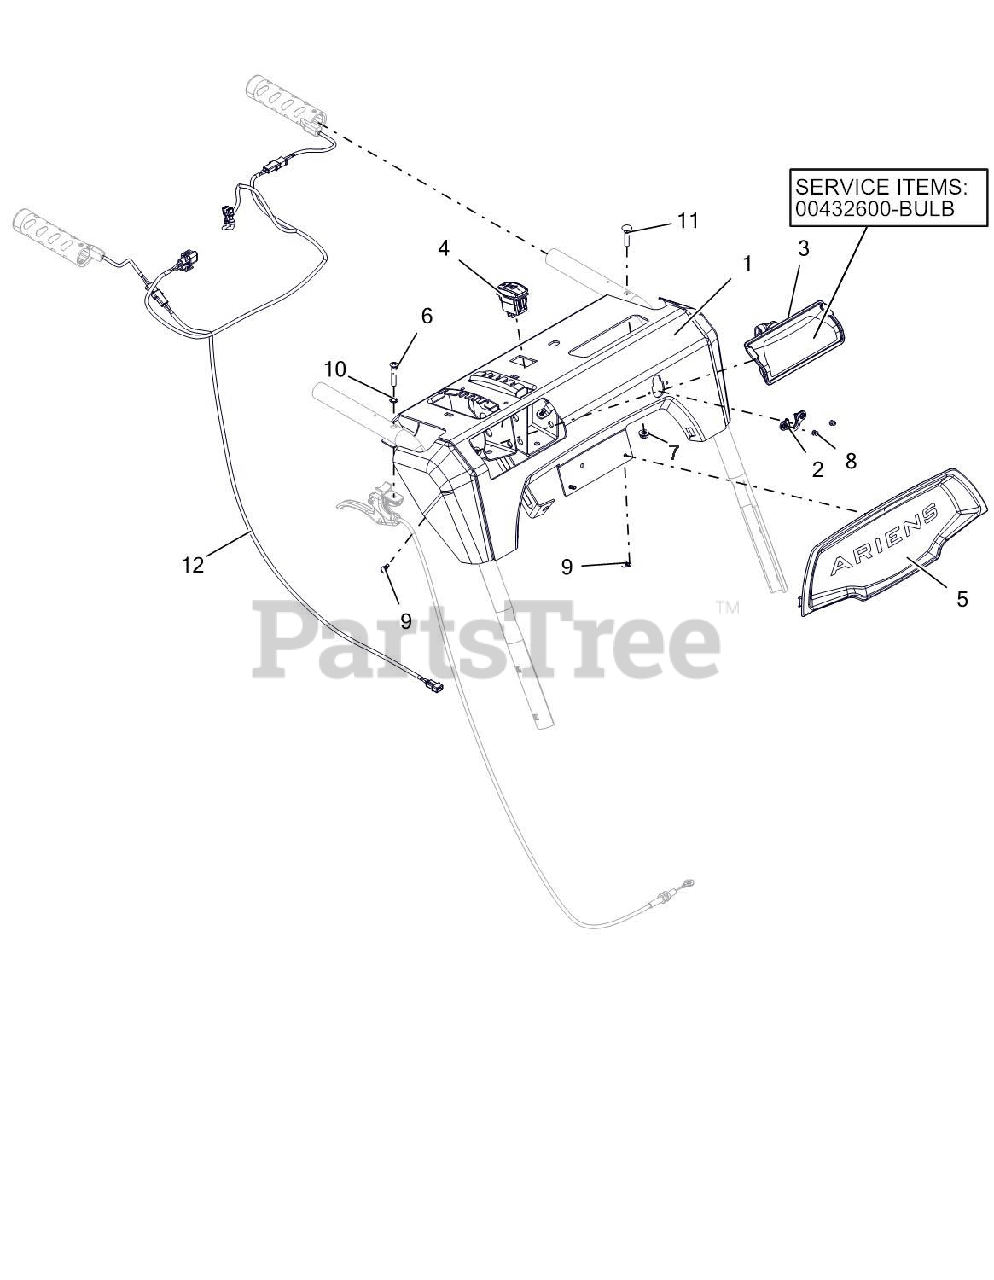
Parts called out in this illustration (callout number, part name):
1	CONTROL PANEL W/DECAL FRIC-TRK
2	GROMMET, CABLE, QUICK TURN 2
3	BULB, LIGHT-HALOGEN 20W
3	HEADLIGHT ASY, HALO 20W 2SHOT
4	SWITCH,ROCKER SPST-ON/OFF
5	BEZEL, DASH - ARIENS LG DASH
6	SCR-MCH .25-20X1.50 OVAL HD
7	@NUT-LK-CTR-FLG .25-20 YWZC
8	RVT-POP #43 .125X.313 STL ZINC
9	SCR-TAP #10X.50 BOSS INDHXHD
10	WSHR-LK-INT .250 TH TYA
11	BLT-RDHDXLSQNK.25-20X1.25 G5ZC
12	HARNESS, LIGHT & WARMER
